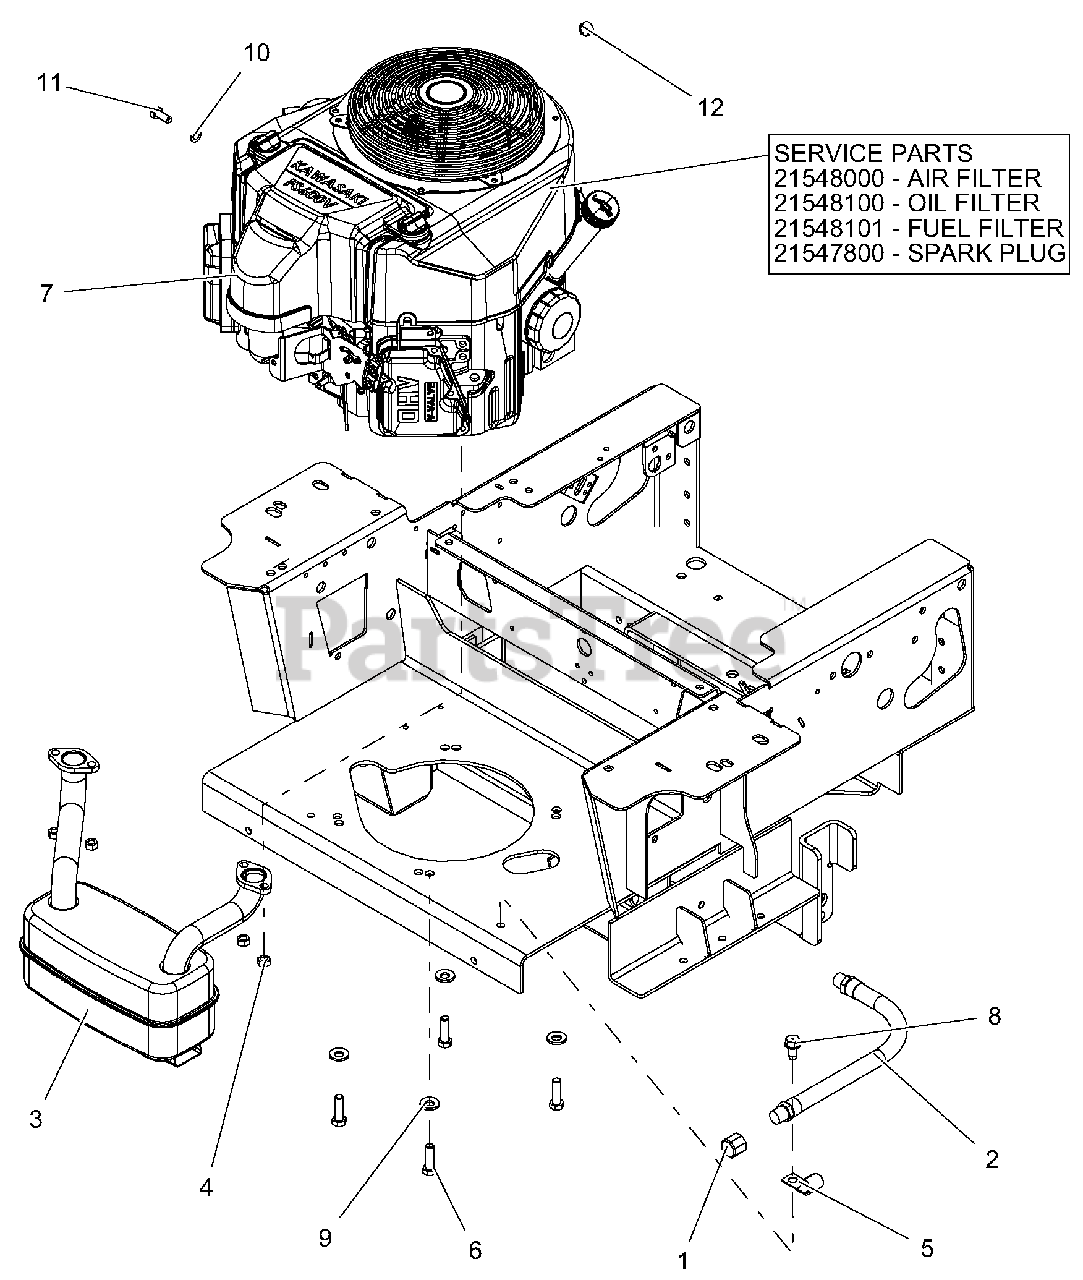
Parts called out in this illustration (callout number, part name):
1	PIPE, CAP 3/8 NPT FEMALE
2	HOSE, HYD .38-11-OK M6N0-M6N0
3	MUFFLER, KAWASAKI
4	NUT-LK-TOP M8-1.25 YWZC
6	BLT-HEX .38-16X1.25 GR5 YWZC NYTORQ
7	ENGINE, KAWASAKI FS730
7	AIR FILTER
7	OIL FILTER
7	FUEL FILTER
7	SPARK PLUG
8	SCR-TAP .38-16X.75 HWH TR YWZ
9	WSHR, 3/8" SPRING DISC
10	WSHR-LK .31X.078 REG YWZC
11	@BLT-HEX M8-1.25X20 YWZC
12	CLAMP, FUEL LINE
